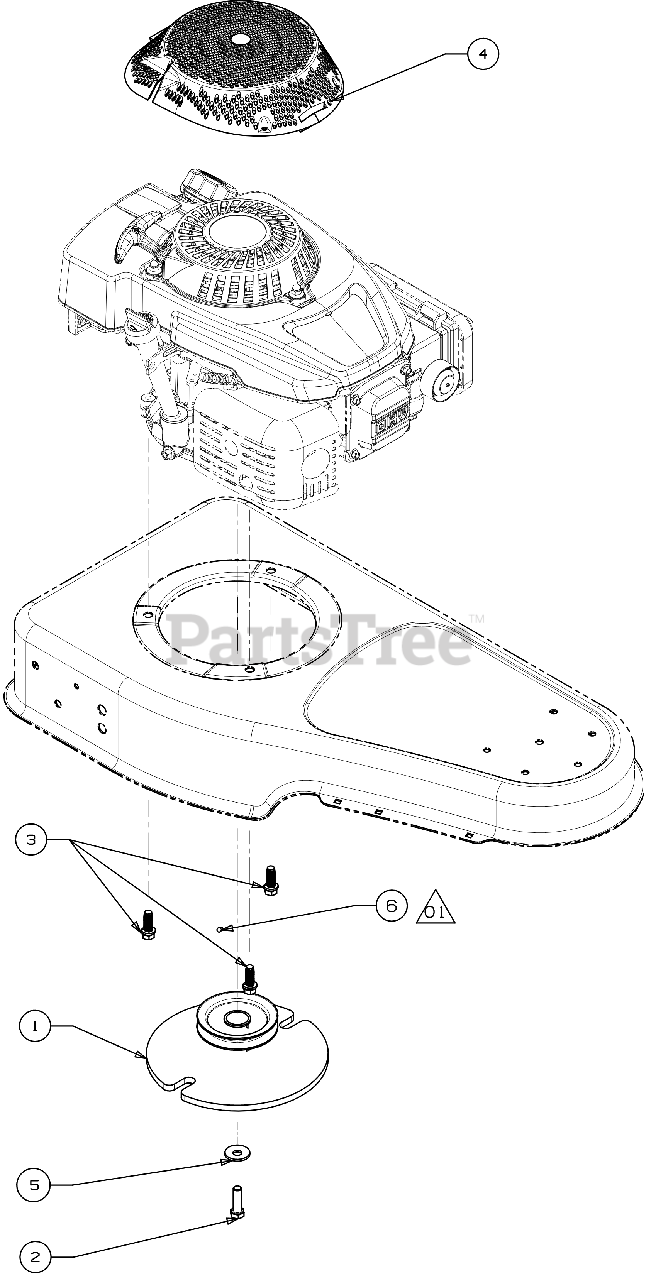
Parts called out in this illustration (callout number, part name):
1	FLYWHEEL PULLEY
2	SCREW 3/8-24 x 1.25 GR8
3	SCREW 3/8-16 x 1
4	SHROUD DEBRIS COVER
5	BELL WASHER
